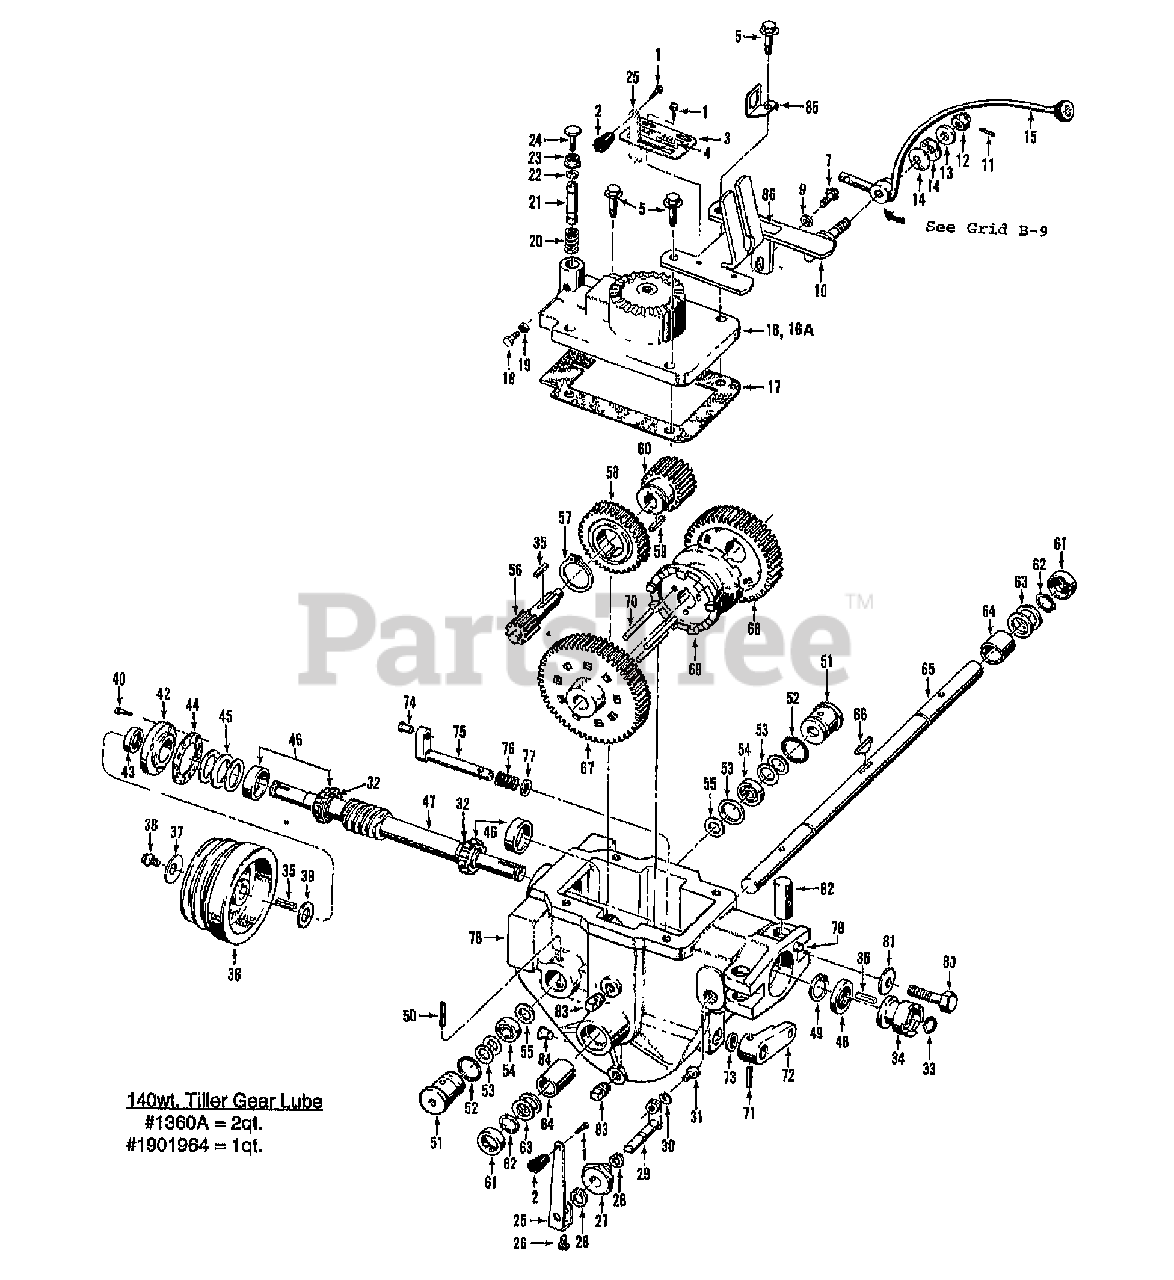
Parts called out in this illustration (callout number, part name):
1	SCR 10-32
2	KNOB-TAPERED
3	PLATE-TINE ENGAGE W/DECAL
4	DECAL-TINE ENGAGE
5	SCR-HFLK 3/8-16X1.50
6	THIS REF. NO. NOT USED
7	SCR-HFLK 5/16-18X.75 ZP
8	THIS REF. NO. NOT USED
9	WASHER-FLAT 5/16 SAE
10	BRKT-H HOOD 2149
11	PIN-SPRING .125 X 1
12	NUT-HEX 1/2-20
13	WASHER-# SHOULDER ZP
14	WASHER-# 1.97X1X.118
15	THIS REF. NO. NOT USED
16	COVER-TRANS RED 2523
16A	ASSM-TRANS COVER OPC
17	GASKET-TRANS COVER
18	SCR-HH 5/16-18X1.0 G5 ZP
19	NUT-HEX 5/16-18 ZP
20	SPRING-REV PLUNGER ZP
21	ASSM-NEUTRAL PLUNGER
22	RING-KLIP EXT .594 ID ZP
23	NUT-HFLK 3/8-16 ZP
24	SCR 3/8-16X1.5 UNC-2AG
25	LEVER-ECCENTRIC RED
26	SCR-HH 1/4-20X.5 GR5 YEL
27	BUSHING-.87X.5X.62 ECC
28	RING-RETAINING 5100-50
29	SHAFT-WELD ECCENTRIC
30	WASHER-LK .25 HI-COLLAR
31	SCR-HXSKT 1/4-20X.38 G8
32	SHIM-1.0X.7656X.062
33	RING-RETAIN EXT .707 ID
34	KIT-CLUTCH DOGS TILLER
34	CLUTCH-DOG HORSE TRANS
35	KEY-.188 SQX1.0
36	SCR-HH 5/16-24X.75 G5 ZP
37	WASHER-.827X.331X.098
38	PULLEY-TRANS MACH
39	WASHER-SHLDR HARDENED
40	SCR-HFLK 1/4-20X.75 G5 ZP
41	THIS REF. NO. NOT USED
42	COVER-FRONT
43	SEAL-PINION SHAFT PT/85030/00
44	GASKET-BRG COVER
45	SHIM-1.75X1.5X.01
45	SHIM-1.75X1.5X.03
45	SHIM-1.75X1.5X.005
45	SHIM-1.75X1.5X.062
46	KIT-BRG CONE&RACE-DRIVESHAFT
47	KIT-WHEELDRIVE ROLL/WORM
48	SEAL-OIL DRIVESHAFT
49	RING-RETAINING 5000-181
50	PIN-SPIROL .25 X 2.0
51	PLUG-PINION BRG W/RING
52	RING-O 1 ID
53	SHIM-1.234X1.015X.033
53	SHIM-1.234X1.015X.062
53	SHIM-1.234X1.015X.01
54	BRG-BALL (7 BALLS)
55	WASHER-# 1X.484X.06
56	GEAR-SPLINE 10 TEETH MACH
57	RING-RETAINING 5100-150
58	GEAR-WORM MACH
59	KEY
60	GEAR-SPUR 20 TEETH MACH
61	SEAL-OIL WHEELSHAFT
62	RING-HEAVY EXT .906 ID
63	SHIM-1.375X1.015X.062
63	SHIM-1.375X1.015X.03
63	SHIM-1.375X1.015X.015
63	SHIM-1.375X1.015X.01
63	SHIM-1.375X1.015X.005
64	BUSHING-1.25X1.005X1.5
65	KIT-WHEELSHAFT
66	KEY-HI PRO .25X1.812
67	GEAR-SPUR 56 TEETH MACH
68	GEAR-SPUR 46 TEETH MACH
69	CLUTCH-MACH
70	PIN-CLUTCH .25 2.65
71	PIN-SPIROL .188 X 1.25
72	LEVER-ECC. #1029
73	SEAL-OIL ECCENTRIC
74	PIN-.375 X .72
75	SHAFT-ECCENTRIC HORSE TLR
76	SPRING .845 X 1.25
77	WASHER # .875 X .65 X .06
78	CASE-TRANS W/PIN
79	PIN-DRIVE .375X.75 ZP
80	SCR-HH 1/2-13X2.0 G5 ZP
81	WASHER-DISC SPRING
82	POST (TC)
83	PLUG-PIPE 1/4 NPT
84	PLUG-CAP (RED)
85	CLIP-CONNECTOR
86	DECAL-FWD INTERLOCK WIRE
